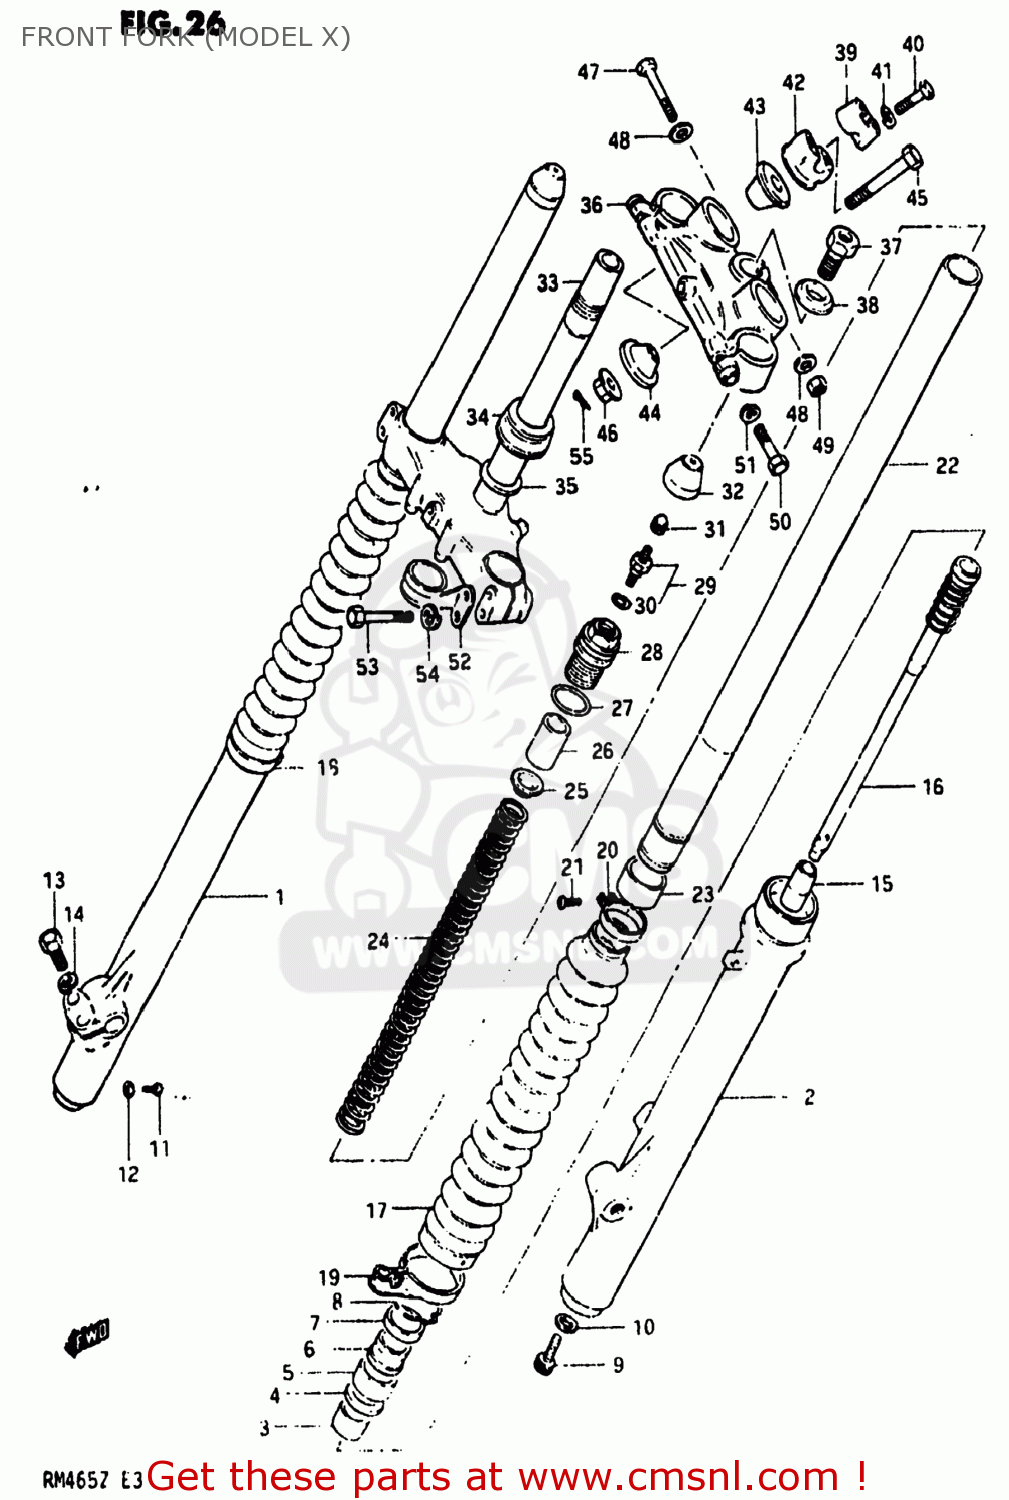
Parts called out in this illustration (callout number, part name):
1	TUBE,OUTER,RIGHT
2	TUBE,OUTER,LEFT
3	METAL,SLIDE
4	WASHER
5	OIL SEAL,FRONT FORK
6	SEAL,DUST
7	CASE,DUST SEAL
8	RING,STOPPER
9	BOLT(14X25)
10	GASKET (NAS)
11	SCREW
12	GASKET,DRAIN,PLUG (NAS)
13	BOLT (8X30)
14	WASHER,LOCK,8.
15	PIECE,OIL LOCK
16	CYLINDER,FRONT FORK
17	BOOT,FRONT FORK COVER
18	BAND,FRONT FORK COVER
19	BAND,FRONT FORK COVER
20	BAND,FRONT FORK BOOT
21	SCREW 4X10
22	TUBE,FORK,INNER
23	PISTON
24	SPRING,FRONT FORK
25	GUIDE,SPRING
26	SPACER,FRONT FORK SPRING
27	O RING
28	CAP,FORK INNER TUBE
29	VALVE,FRONT FORK AIR
30	O-RING
31	CAP,VALVE AIR
32	CAP
33	STEM,STEERING
34	BEARING
35	WASHER,THRUST
36	HEAD,STEERING STEM
37	BOLT
38	WASHER
39	HOLDER,HANDLEBAR
40	BOLT
41	WASHER,LOCK,8.
42	HOLDER,HANDLEBAR
43	DAMPER,UPR
44	DAMPER,LWR
45	BOLT,HANDLE HOLDER
46	NUT
47	BOLT 8X50
48	WASHER
49	NUT
50	BOLT
51	WASHER,LOCK,8.
52	GUIDE,CABLE
53	BOLT 8X40
54	WASHER,LOCK,8.
55	PIN 20X20
